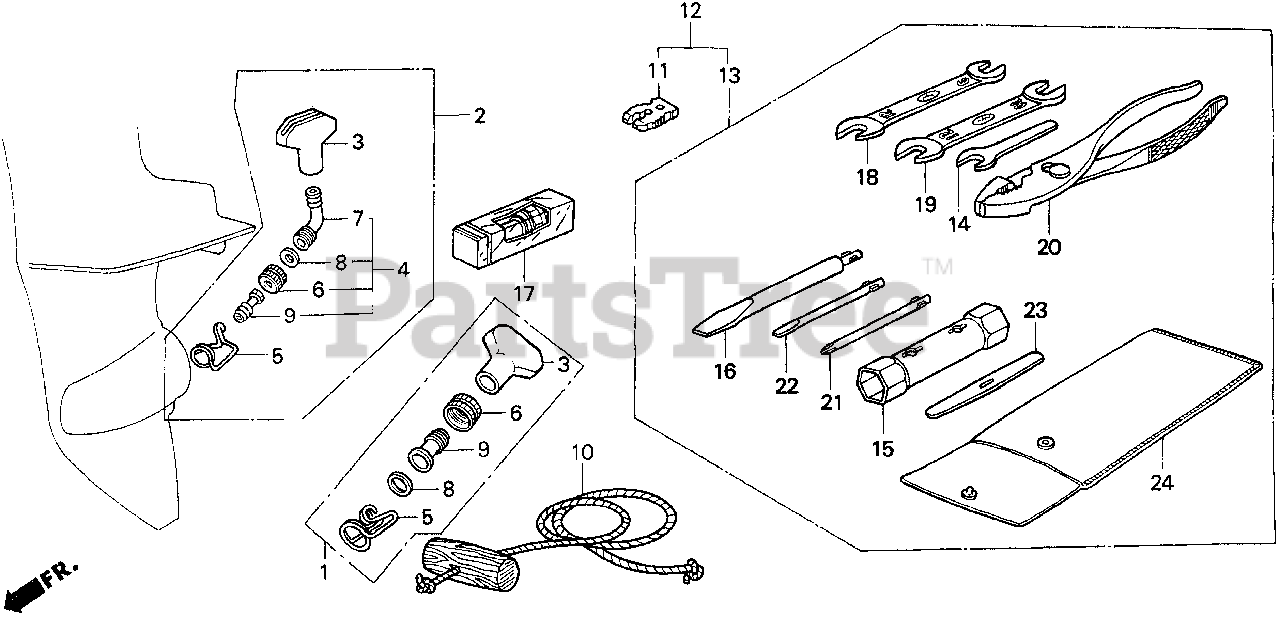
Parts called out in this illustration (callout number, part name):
2	WATER MOUTH KIT
2	MOUTH SET, WATER
3	MOUTH, WATER
5	CLIP, WATER MOUTH
6	NUT, WATER MOUTH
7	JOINT, WATER MOUTH
8	SEAT, WATER MOUTH
9	JOINT, HOSE
10	ROPE, STARTER (#5X55")
13	TOOL SET (N/A: SEE COMPONENTS)
14	WRENCH (8MM) (OPEN END) (NOT AVAILABLE)
15	WRENCH, BOX (P18X19) (NOT AVAILABLE)
16	SCREWDRIVER, CHECK BOLT
17	SPARK PLUG (DR5HS) (NGK)
18	WRENCH (9X12) (OPEN END)
19	WRENCH (10X12) (OPEN END)
20	PLIERS (135MM)
21	SCREWDRIVER 1, PHILLIPS (NO.2)
22	SCREWDRIVER 3, STRAIGHT SLOT (NO.2)
23	LEVER, TIRE
